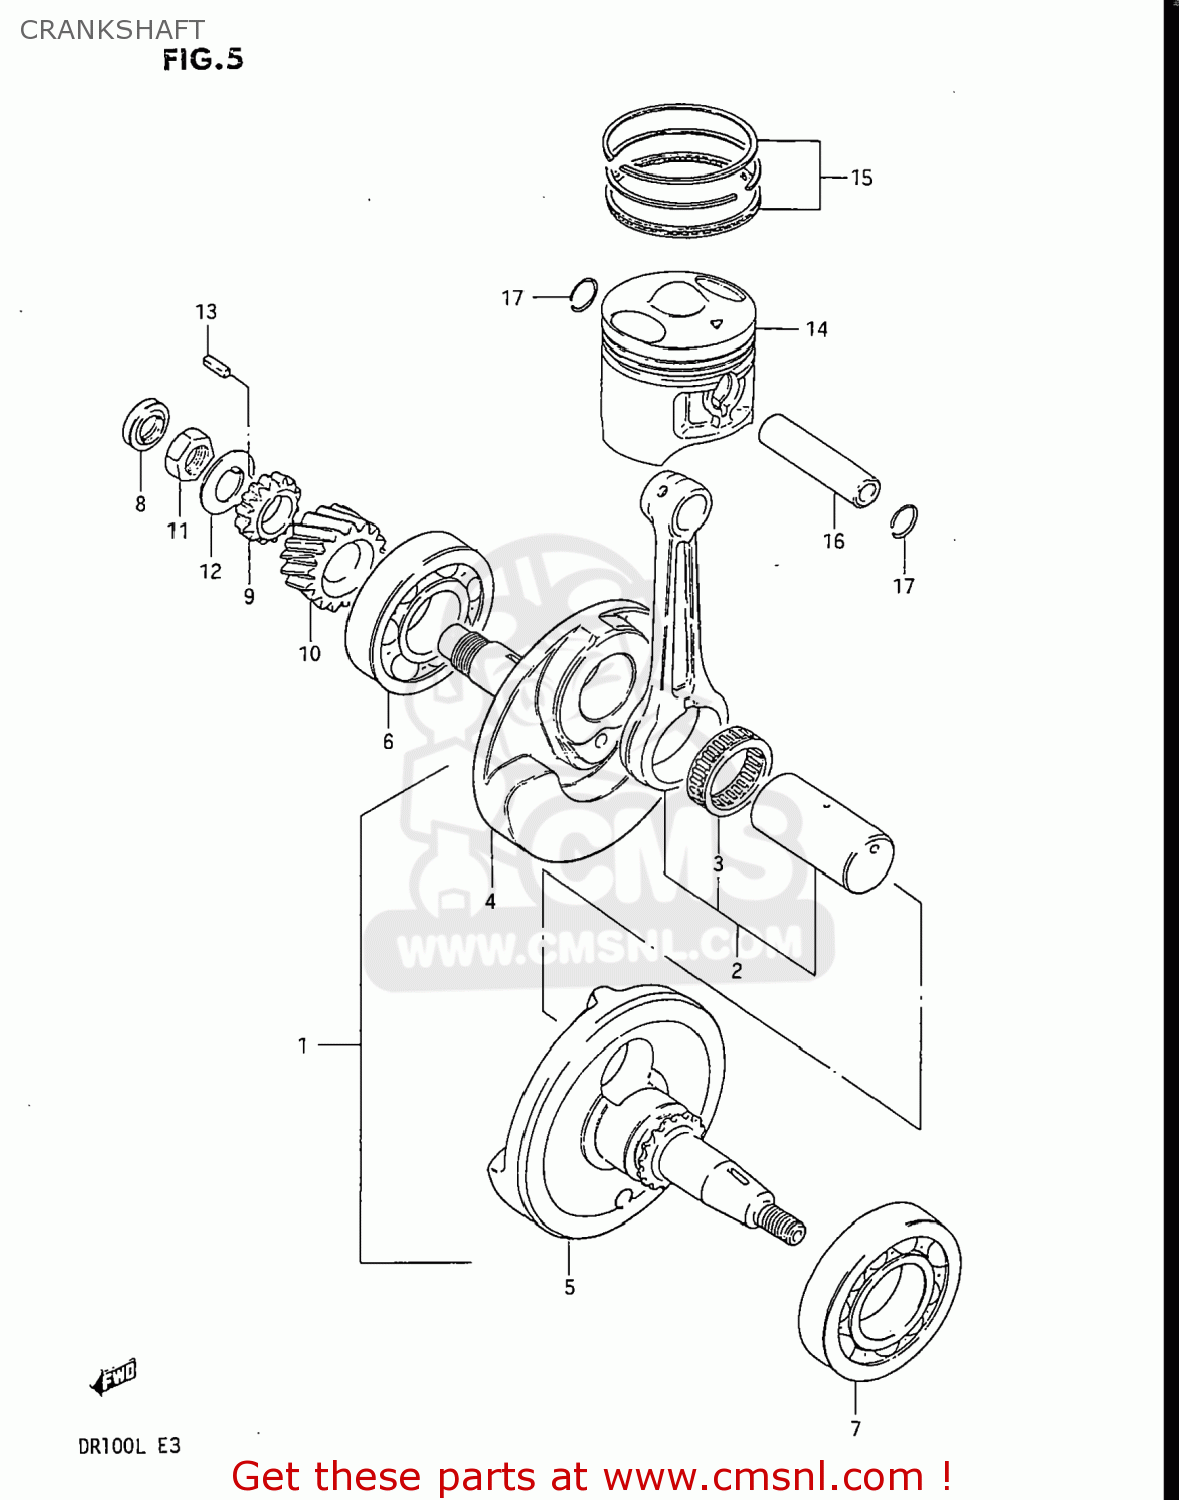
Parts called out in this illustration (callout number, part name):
1	CRANKSHAFT ASSEMBLY
2	CRANKSHAFT ASSEMBLY
3	BEARING
4	CRANKSHAFT,RIGHT
5	CRANKSHAFT,LEFT
6	BEARING(28X68X18)
7	BEARING(35X72X17)
8	OIL SEAL
9	GEAR,OIL PUMP DRIVE
10	GEAR,PRIMARY DRIVE
11	NUT
12	WASHER
13	KEY
14	PISTON (51.00MM)
15	RING SET,PISTON
16	RING,PISTON
17	RING,SNAP 14MM
